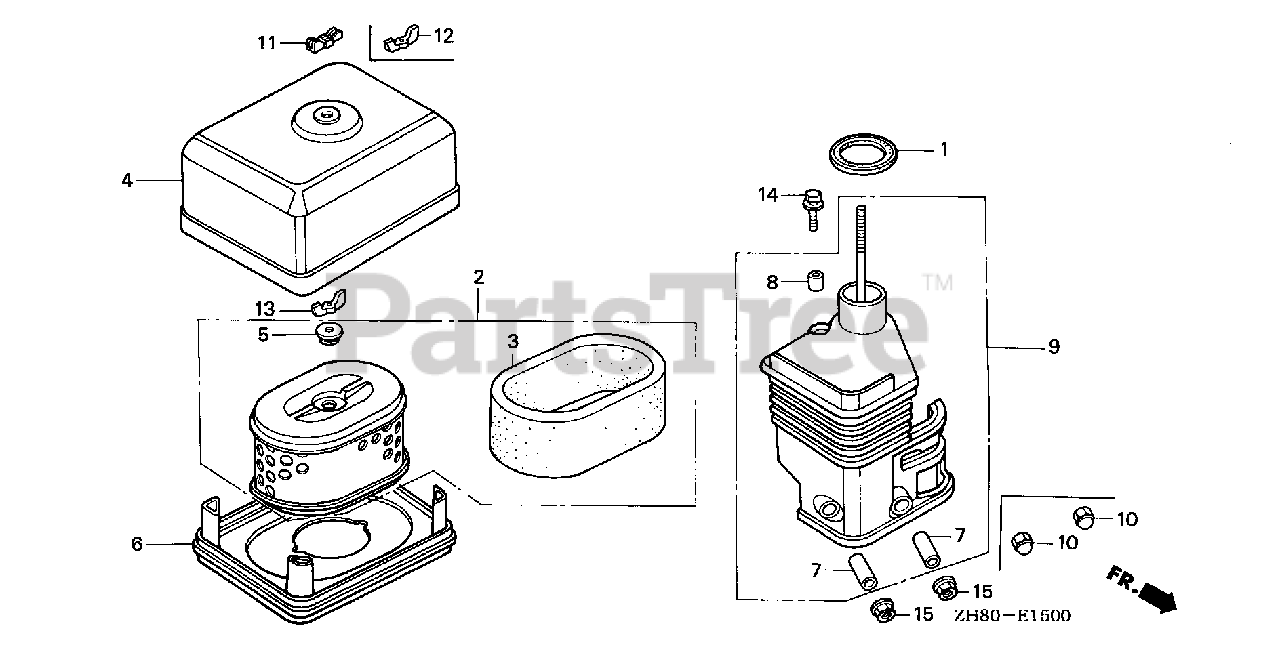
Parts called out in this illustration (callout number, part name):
1	GASKET, ELBOW
2	ELEMENT, AIR CLEANER (DUAL)
3	FILTER (OUTER)
4	COVER, AIR CLEANER (DUAL)
5	GROMMET, AIR CLEANER
7	COLLAR, AIR CLEANER
8	COLLAR B, AIR CLEANER
9	ELBOW, AIR CLEANER
10	NUT, CAP (6MM)
11	NUT, AIR CLEANER COVER (DACRO COATING)
11	WINGNUT (6MM) (BLACK)
12	NUT, TOOL BOX SETTING
13	NUT, TOOL BOX SETTING
14	BOLT-WASHER (6X20)
15	NUT, FLANGE (6MM)
